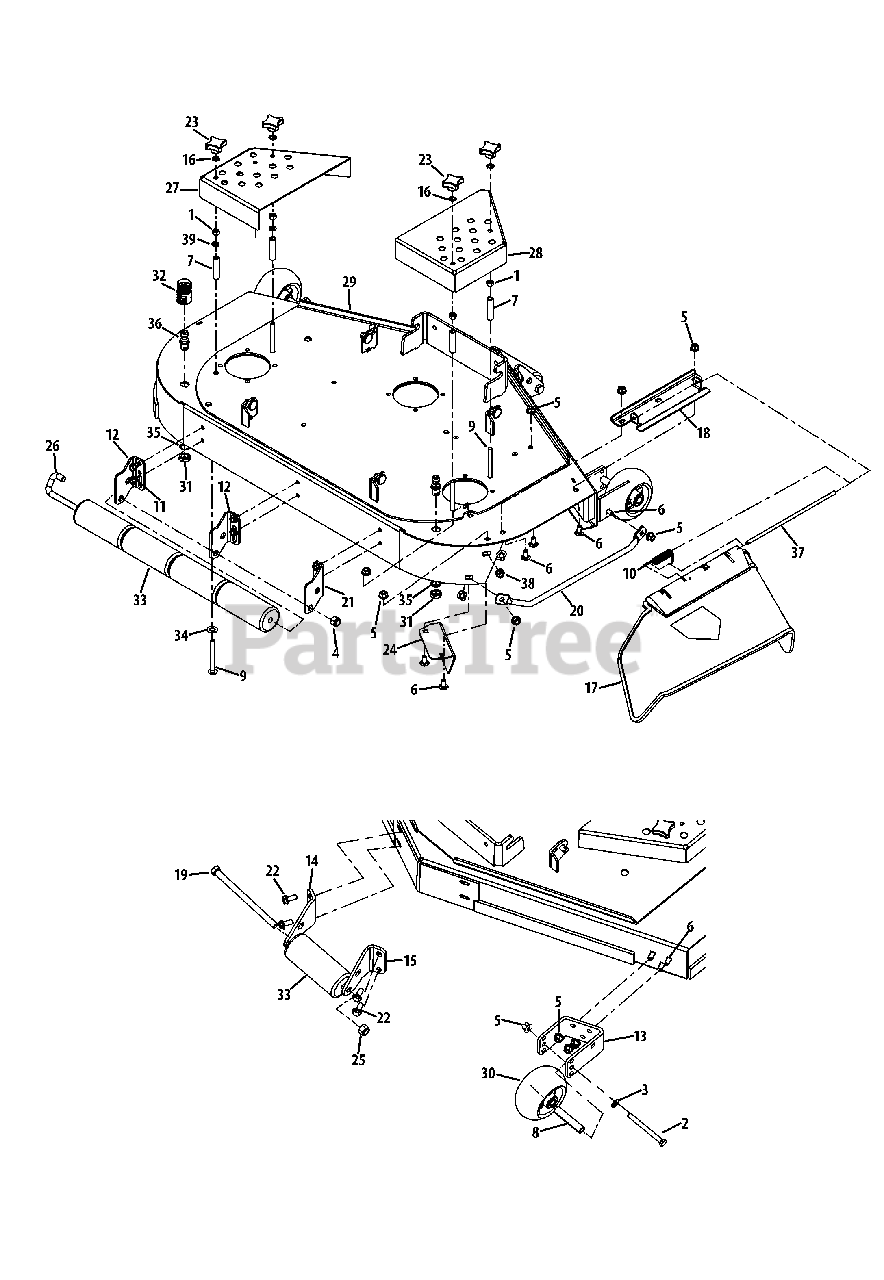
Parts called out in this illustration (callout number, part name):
1	Nut, 3/8-16
2	Hex Screw, 3/8-16 x 4.00
3	Flat Washer, .406 x .812 x .051
4	Hex Lock Nut, 1/2-13
5	Counterlock Flange Nut, 3/8-16
6	Carriage Bolt, 3/8-16 x .75
7	Spacer, .400 x .560 x 2.45
8	Spacer, .390 x .620 x 3.04
9	Carriage Bolt, 3/8-16 x 3.50
10	Torsion Spring, .639 x 2.16 x .12
11	Flange Screw, 3/8-16 x .500
16	Lock Washer, 3/8
17	Chute Deflector
18	Chute Deflector Bracket
19	Hex Screw, 1/2-20 x 7.50
20	Finger Guard
22	Screw, 3/8-16 x 1.00
23	Plastic Knob, 3/8-16
24	Micro Chute Baffle
25	Nut, 1/2-20
26	J-Hook w/ Threaded Roller
31	Hex Nut
32	Water Nozzle Adapter
33	Front Roller
34	Flat Washer, .510 x 1.00 x .060
35	Lock Washer, 17 x 23.8 x 1.95
36	Water Deck Nozzle
37	Chute Deflector Rod
38	Nut, Flange Lock, 3/8-16, Grf,
39	Washer, Lock, 3/8 , Regular Duty
